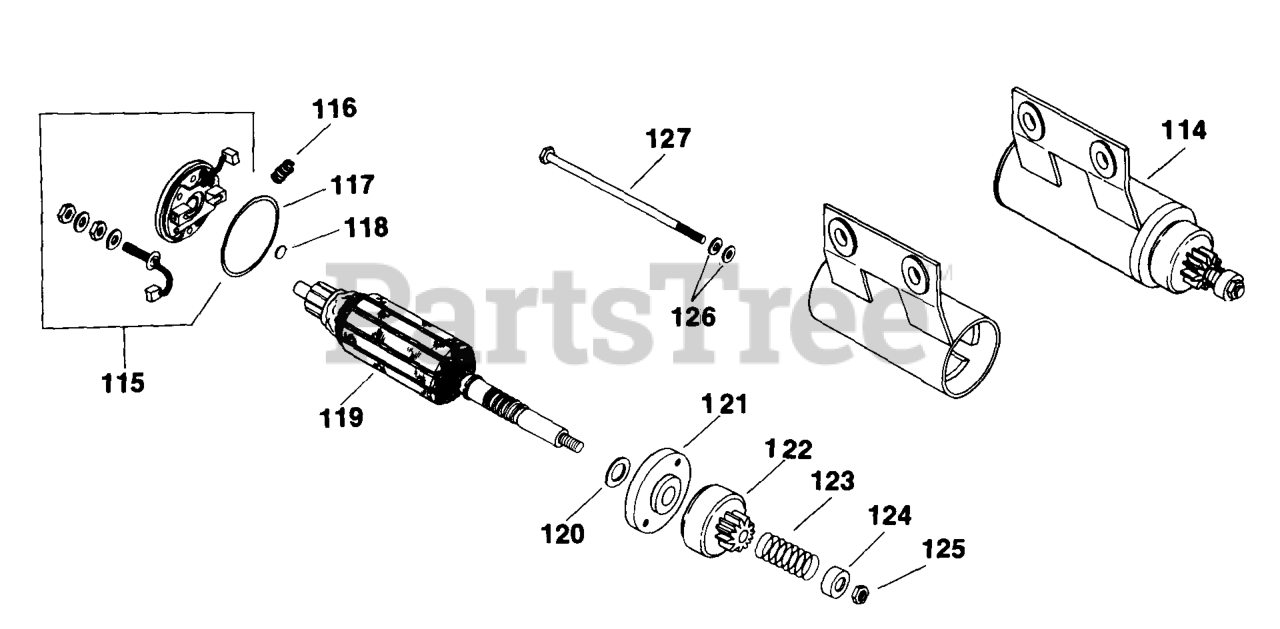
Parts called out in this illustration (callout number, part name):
115	CAP - DISCONTINUED
116	SPRING - DISCONTINUED
117	GASKET - DISCONTINUED
118	THRUST DISC - DISCONTINUED
119	ARMATURE - DISCONTINUED
120	WASHER - DISCONTINUED
121	CAP - DISCONTINUED
122	DRIVE - DISCONTINUED
123	SPRING - DISCONTINUED
124	PINION STOP - DISCONTINUED
125	KIT, THREE WAY VALVE
